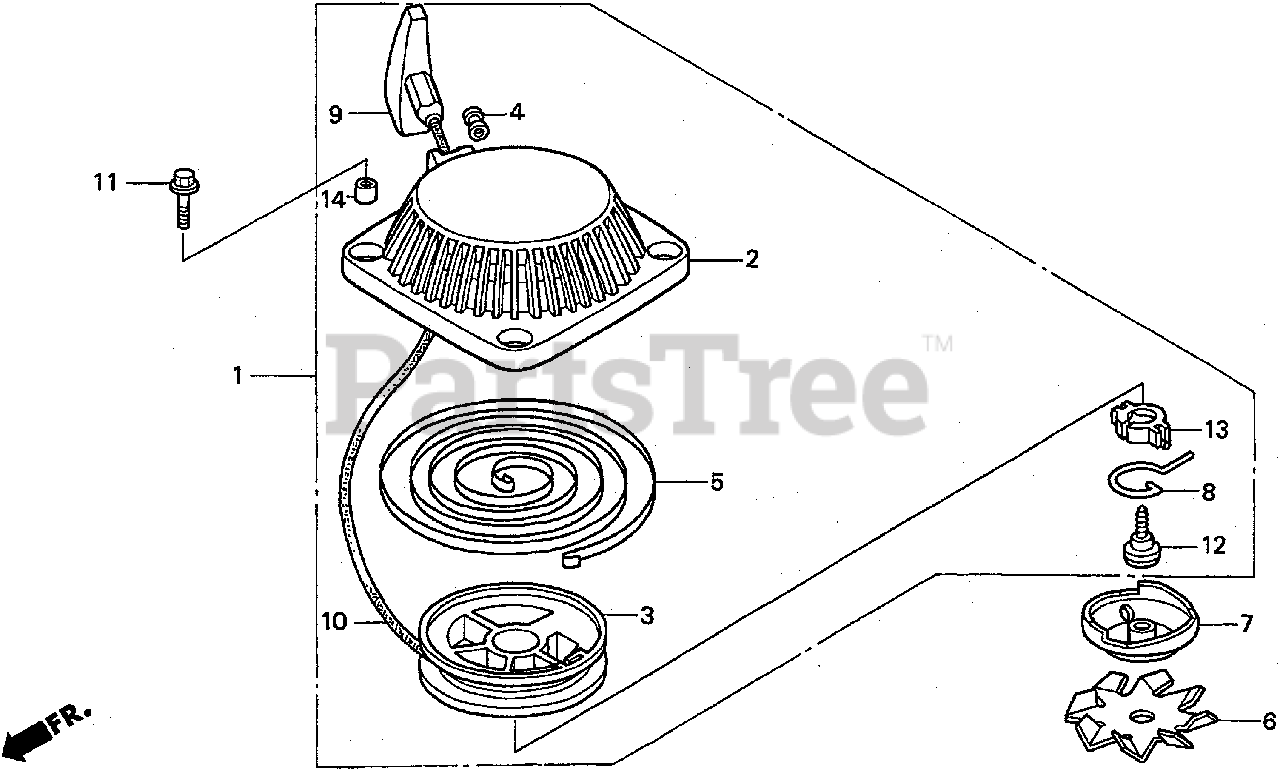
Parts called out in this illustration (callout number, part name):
1	STARTER ASSY., RECOIL *NH1* (BLACK)
2	CASE, RECOIL STARTER
3	REEL, RECOIL STARTER
4	GUIDE, ROPE
5	SPRING, RECOIL STARTER
6	FAN, RATCHET
7	PULLEY, RECOIL STARTER
8	SWINGARM
9	KNOB, RECOIL STARTER
10	ROPE, RECOIL STARTER
11	BOLT, FLANGE (5X18)
12	SCREW, SETTING
13	COLLAR
14	COLLAR
